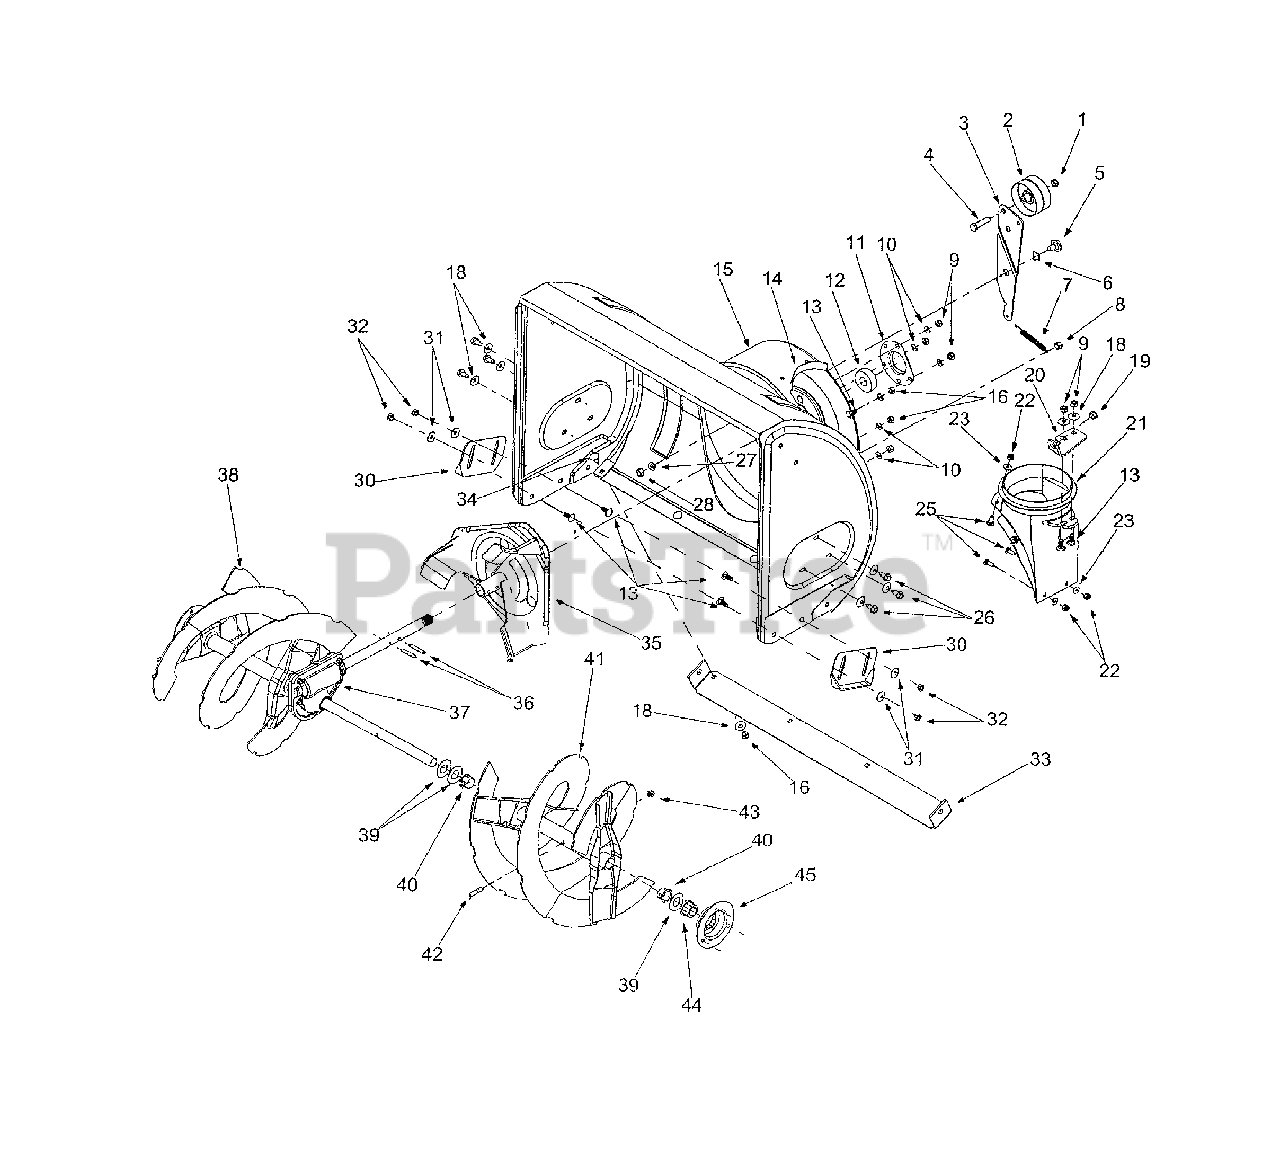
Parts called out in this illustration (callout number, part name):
1	Lock Jam Nut 3/8-24
2	Flat Idler
4	Hex Cap Screw 3/8-24 x 1.50
5	Shoulder Screw
6	Wave Washer
7	Extension Spring
8	Hex Nut 5/16-18
9	Hex Nut 5/16-18
10	Lock Washer 5/16
11	Housing
12	Ball Bearing
13	Carriage Bolt 5/16-18 x .75
18	Bell Washer
19	Bushing
21	Chute Adapter
22	Hex Lock Nut 1/4-20
23	Flat Washer
25	Carriage Screw 114-20 x .75
26	Hex Washer Screw 5/16-18
27	Lock Washer 3/8
28	Hex Nut 3/8-16
31	Bell Washer
32	Hex Nut 5/16-18
34	Carriage Bolt 5/16-18 x .62
37	24" Gear Assembly
39	Flat Washer
40	Flange Bushing
42	Shear Bolt 5/16-18 x 1.5
43	Lock Nut 5/16-18
44	Hex Flange Bearing
